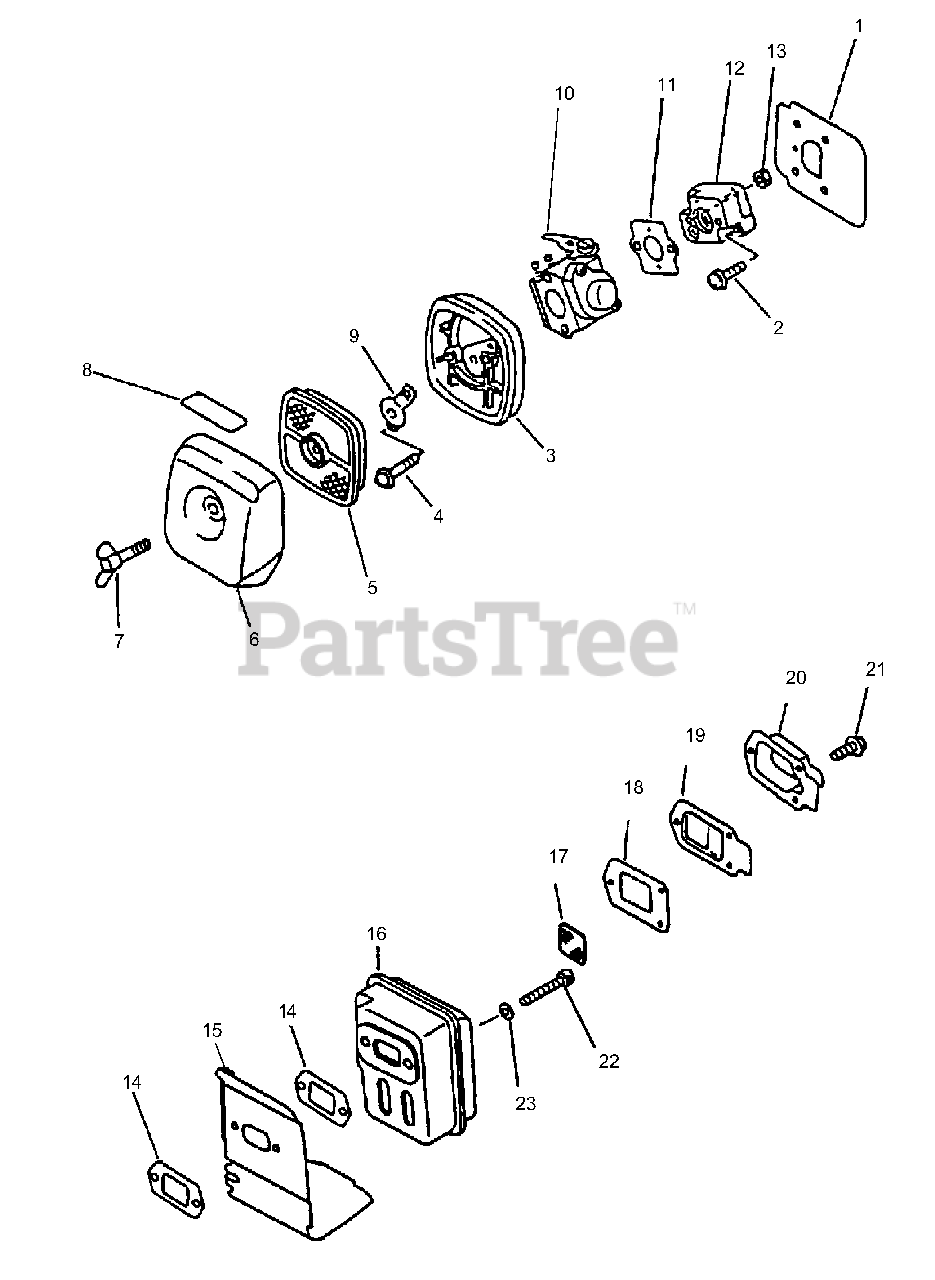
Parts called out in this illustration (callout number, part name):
1	SHIELD, INTAKE
2	SCREW - 5X20
3	AIR FILTER CASE ASSY
4	SCREW - 5X65
5	FILTER, AIR - SINGLE LAYER
6	COVER, AIR FILTER - GRAY
7	THUMBSCREW
8	LABEL - CHOKE
9	PLATE, PREVENT
10	CARBURETOR C1U-K47
10	CARBURETOR C1U-K52
11	GASKET, INTAKE
12	INSULATOR, INTAKE
14	GASKET, EXHAUST
15	COVER, EXHAUST
17	SCREEN, SPARK ARRESTOR
18	GASKET, EXHAUST
19	GASKET, EXHAUST - INNER
20	GUIDE, EXHAUST - OUTER
21	SCREW - 4X10
22	SCREW - 5X55
23	WASHER - 5
